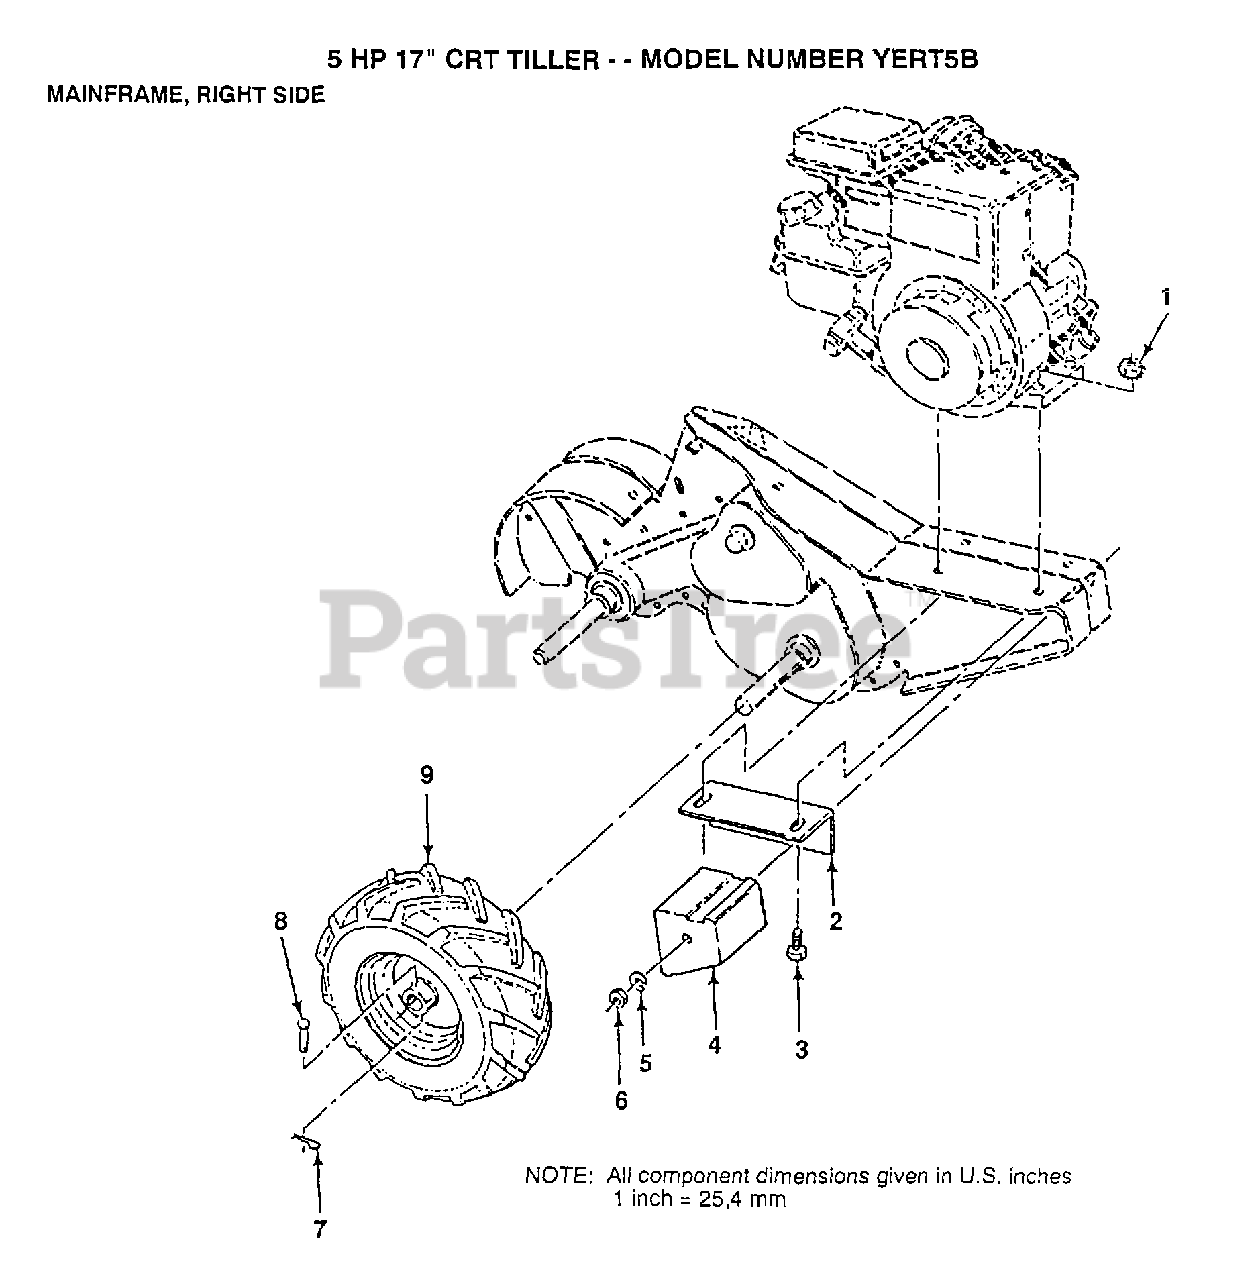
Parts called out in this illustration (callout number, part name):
2	BRACKET RH CRT
3	BOLT.HEX.5/16-1.5
4	COUNTERWEIGHT CRT
5	LOCKWASHER
6	NUT.HEX.3/8-16UNC
7	RETAINER M
8	RIVET.DRILL.1.75
9	TIRE.CHV.13X5.0-6
